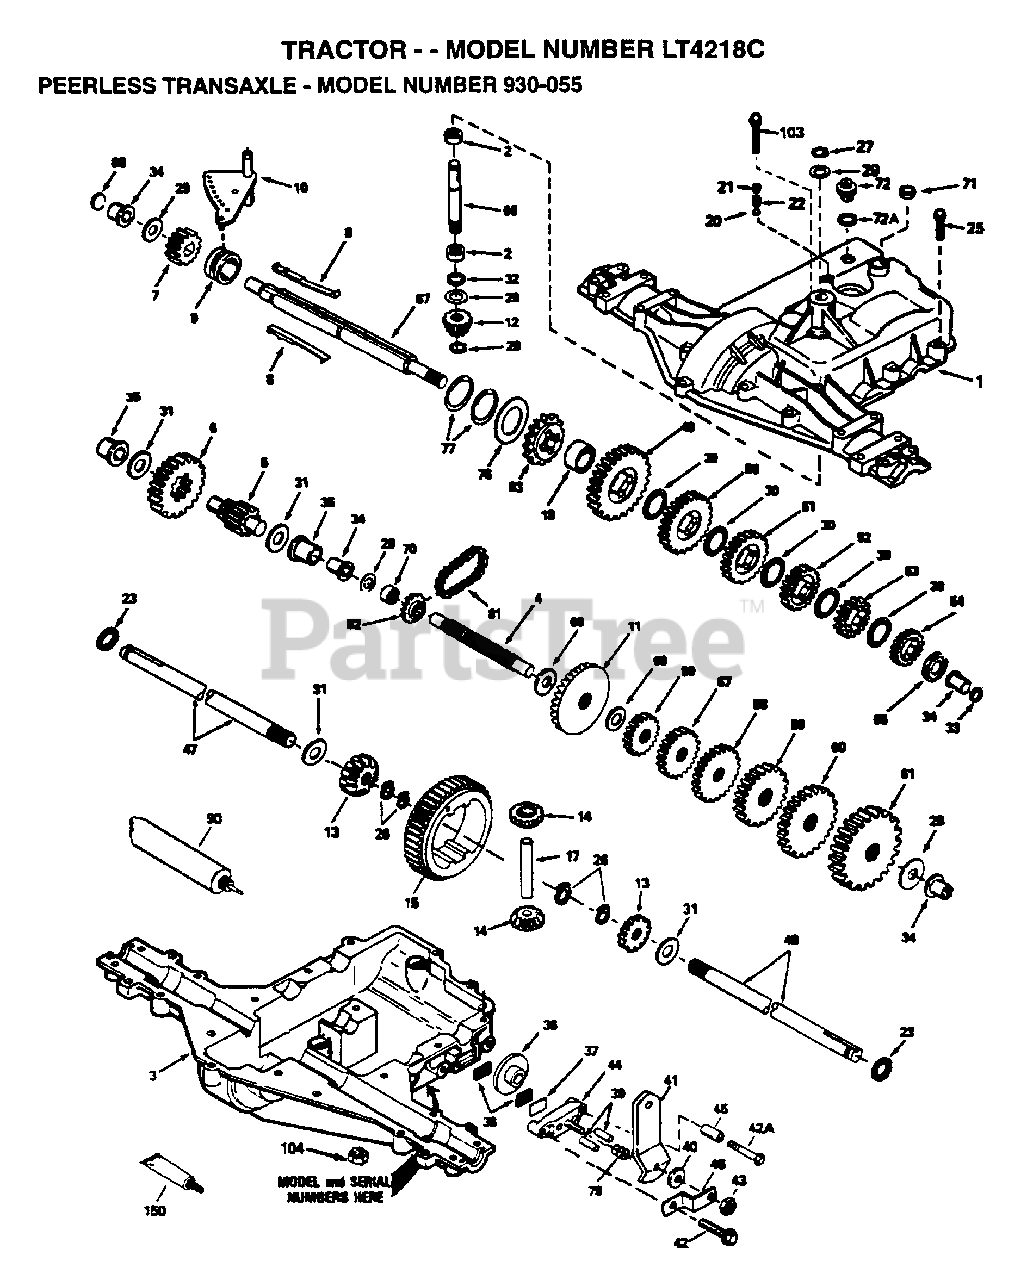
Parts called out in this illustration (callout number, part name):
1	TRANSAXLE COVER
2	BEARING, NEEDLE
3	TRANSAXLE CASE
4	SHAFT, COUNTER
5	OUTPUT SHAFT AND PINION
6	GEAR, OUTPUT
7	GEAR, SPUR, 15 TEETH
9	COLLAR, SHIFTER
10	ROD & FORK ASSY, SHIFT
11	GEAR, BEVEL, 42 TEETH
12	BEVEL PINION, INPUT
13	GEAR, BEVEL
14	GEAR, BEVEL, PINION
18	SPACER, NEUTRAL
20	BALL STEEL, 5/16" DIA.
21	SCREW, 3/8-16 X 3/8"
25	SCREW, 1/4-20 X 1-1/4
26	RING RETAINER
27	RING, RETAINER
28	RETAINING RING
29	WASHER THRUST
30	WASHER THRUST
33	SEAL, SQUARE CUT
34	BUSHING, FLANGED
35	BUSHING, FLANGED
36	DISK, BRAKE
37	PLATE BRAKE PAD
41	BRAKE LEVER
42	SCREW, 1/4-20 X 1-1/4
42A	SCREW, 1/4-20 X 2-1/4
43	LOCKNUT 5/16-24
44	HOLDER BRAKE PAD
46	BRKT BRAKE LEVER
49	GEAR, SPUR, 37 TEETH
50	GEAR, SPUR, 35 TEETH
51	GEAR, SPUR, 30 TEETH
52	GEAR, SPUR, 25 TEETH
53	GEAR, SPUR, 22 TEETH
54	GEAR, SPUR, 19T
56	GEAR, SPUR, 12 TEETH
57	GEAR, SPUR, 15 TEETH
58	GEAR, SPUR, 20 TEETH
59	GEAR, SPUR, 25 TEETH
60	GEAR, SPUR, 28 TEETH
61	GEAR, SPUR, 31 TEETH
65	WASHER, THRUST
66	SHAFT, INPUT
67	SHAFT, BRAKE, 4 KEYED
69	WASHER THRUST
71	SEAL SQUARE CUT
72	THREADED PLUG 9/16-18
76	WASHER, THRUST
77	INVERTED RETAINING RING
81	CHAIN, ROLLER
82	SPROCKET 9T
83	SPROCKET 18T (REV)
90	GREASE BENTONITE, 32 OZ.
150	GASKET ELIMINATOR
